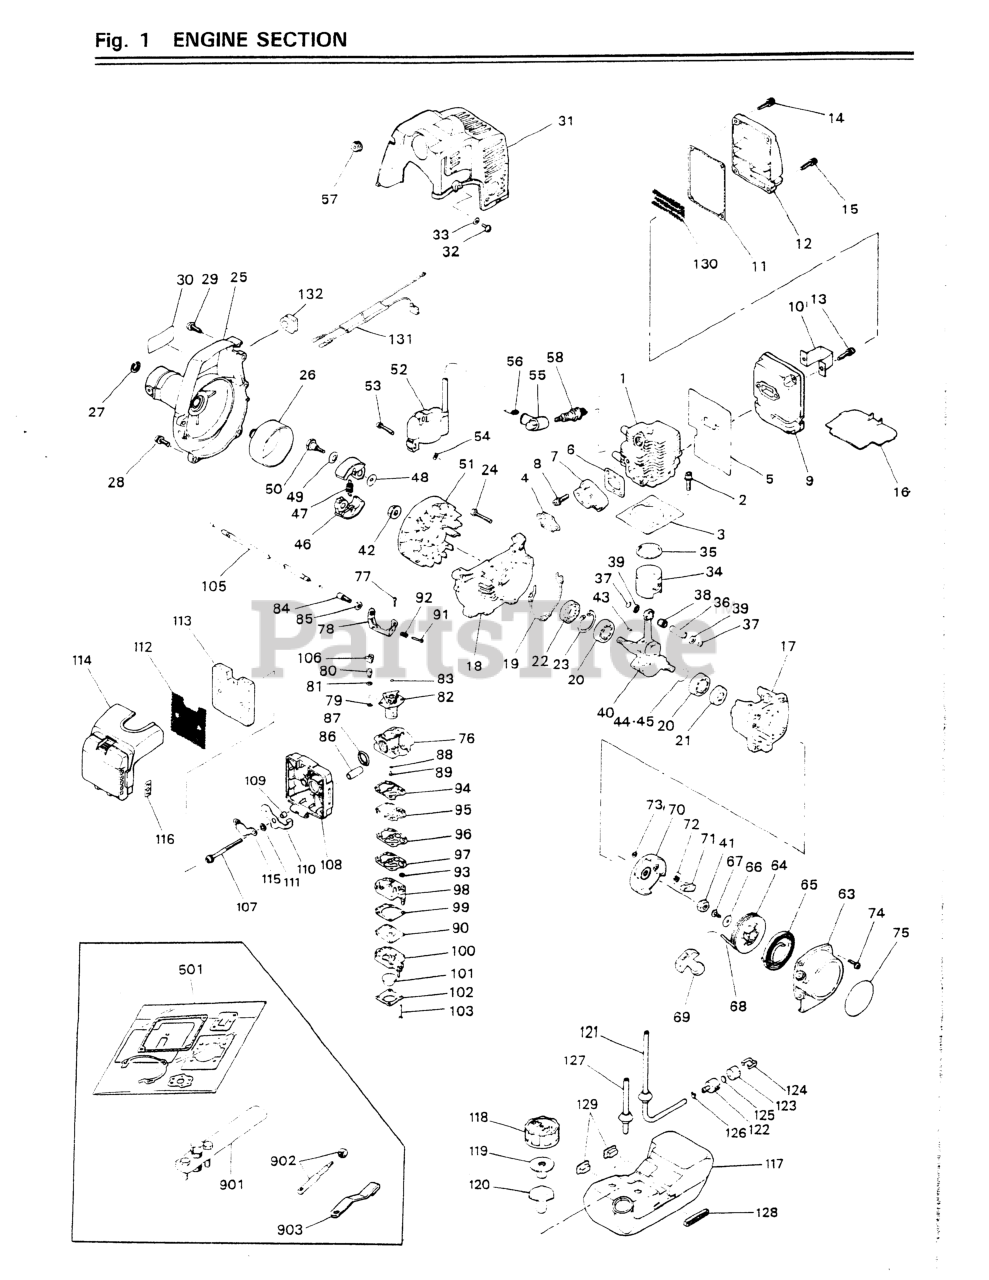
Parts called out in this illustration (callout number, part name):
2	BOLT, M5 X 22
8	SCREW, M5 X 20
13	BOLT, M6 X 18
14	BOLT, M5 X 22
15	BOLT (USE 3310-31720)
17	CRANKCASE (RPLS -21100)
18	CRANKCASE (RPLS -21100)
20	BEARING
22	SEAL, OIL (RPLS 1140-21220)
23	RING, SNAP, M28 x 1.2
24	SCREW, M5 x 30
27	RING, SNAP
28	SCREW, M5X20 (RPLS.1400-75510)
29	SCREW, HOUSING
32	SCREW, M4 x 12
33	WASHER
34	PISTON
35	RING, PISTON (RPLS 1850-41210)
36	PIN, PISTON 5x8x26
39	WASHER
43	KEY
45	SHIM (NO LONGER AVAILABLE)
48	WASHER, FLAT (USE 182303)
50	BOLT
53	SCREW, M4 X 22
56	SPRING
57	GROMMET
64	REEL
65	SPRING, SPIRAL
66	WASHER (NO LONGER AVAIL)
72	SPRING, RETURN
73	E-RING
74	SCREW, M4 X 16
75	LABEL
77	SCREW
79	RING
80	SWIVEL (USE -06040)
81	WASHER
82	VALVE ASSY (NO L0NGER AVAIL)
83	PLUG NEEDLE
85	NUT, CABLE ADJUSTER
86	SLEEVE, MOUNT
87	RING, PACKING (NLA)
88	RING, O
90	DIAPHRAGM (USE 4810-81260)
91	SCREW, IDLE AD
92	SPRING, IDLE A
93	SCREEN
94	GASKET, PUMP
95	DIAPHRAGM
96	PLATE, PUMP (NLA)
97	GASKET, PLATE
98	BODY, PUMP
99	KIT ONLY
101	PUMP, PRIMING
102	COVER
103	SCREW
105	CABLE COMP (NLA)
106	CAP, CABLE END
108	BODY (RPLS -82110)
109	SLEEVE
112	SCREEN
113	ELEMENT
114	COVER
115	PLATE
116	LABEL
118	CAP (USE 5601-85201)
119	VALVE (NO LONGER AVAILABLE)
121	PIPE COMP (NO LONGER AVAIL)
122	5500-85400 (RRLS. 1750-85300)
123	FILTER (NLA)
124	RETAINER (NLA)
125	SCREEN (NLA)
126	CLIP (REPLACES 2841-31280)
129	CUSHION (F)
130	ARRESTER
902	(H) ROD ASSY
903	STOPPER (TOOL) (RPLS -96410)
